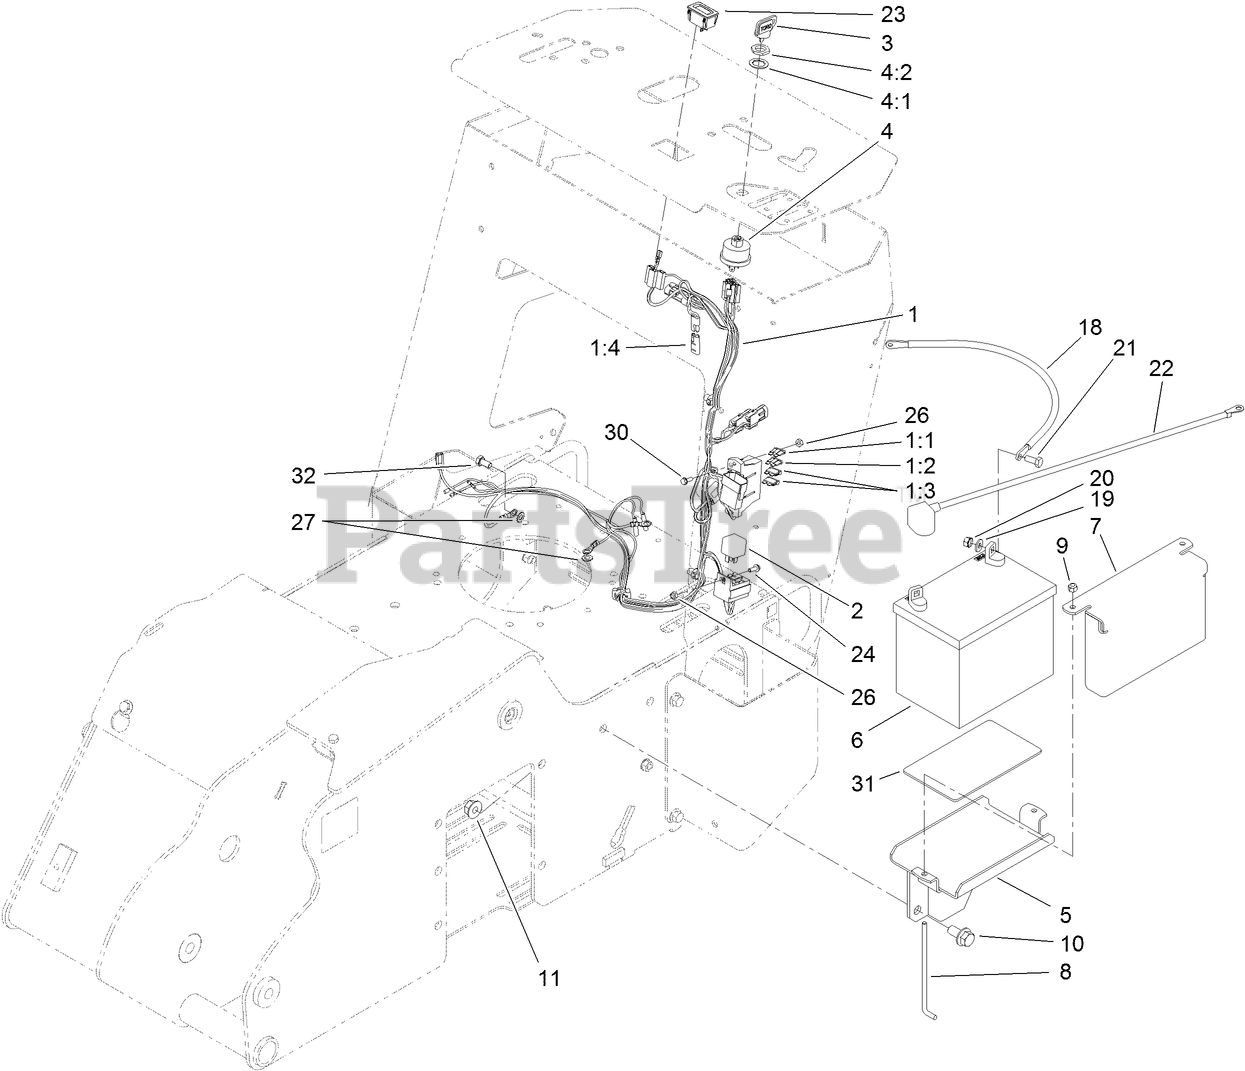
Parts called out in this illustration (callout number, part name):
1	HARNESS-WIRE
1:1	FUSE-BLADE, 30 AMP
1:2	FUSE-BLADE, 25 AMP
1:3	FUSE-BLADE, 20 AMP
1:4	CAP-PLUG
2	RELAY
3	KEY-IGNITION
4	Key Switch ASM
4:1	WASHER-TOOTH, INTERNAL
4:2	NUT-HH
5	TRAY-BATTERY
6	BATTERY-DRY
7	PLATE-HOLD DOWN, BATTERY
8	HOLDOWN-BATTERY
9	NUT-LOCK, NI
10	SCREW-HHF
11	NUT-HHF
18	CABLE-BATTERY, POSITIVE
19	WASHER-FLAT
20	NUT-KEPS
21	SCREW-HH
22	CABLE-BATTERY, BLACK
23	HOURMETER
26	NUT-LOCK, NI
27	WASHER-LOCK
30	SCREW-HWH
31	PAD-SKID, ANTI
32	SCREW-HH
